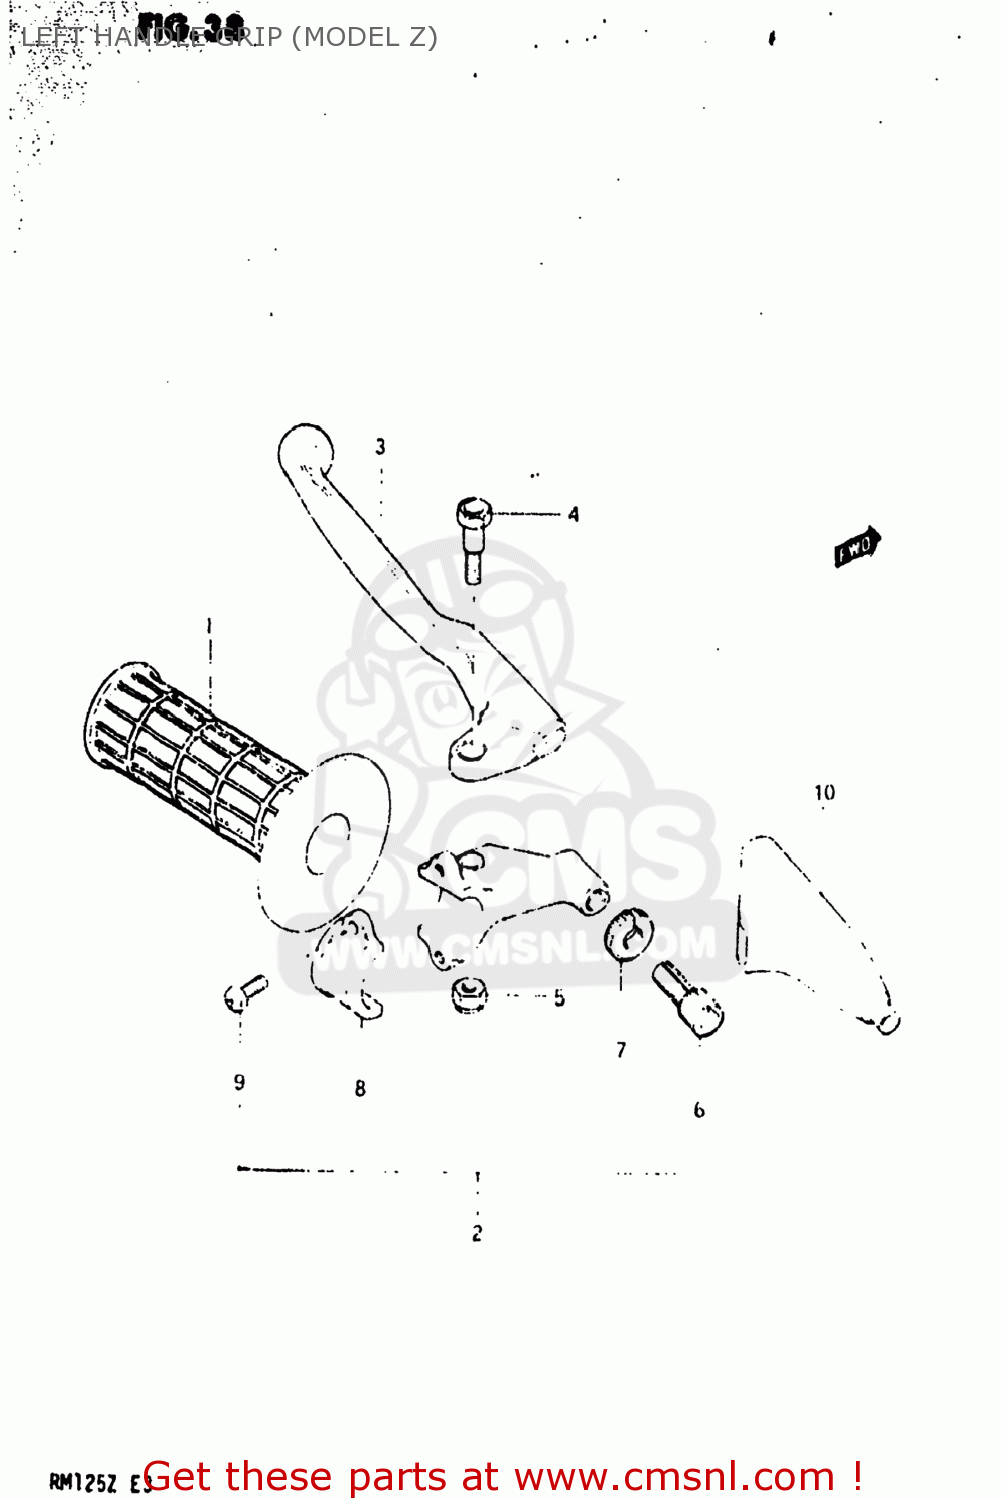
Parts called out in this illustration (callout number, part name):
1	GRIP,LEFT
2	LEVER ASSY,CLUTCH
3	LEVER,CLUTCH
4	BOLT,LEVER
5	NUT 6MM
6	ADJUSTER,CABLE
7	NUT,CABLE ADJUSTER
8	BRACKET,CLUTCH LEVER HOLDER
9	SCREW
10	COVER,CLUTCH LEVER
